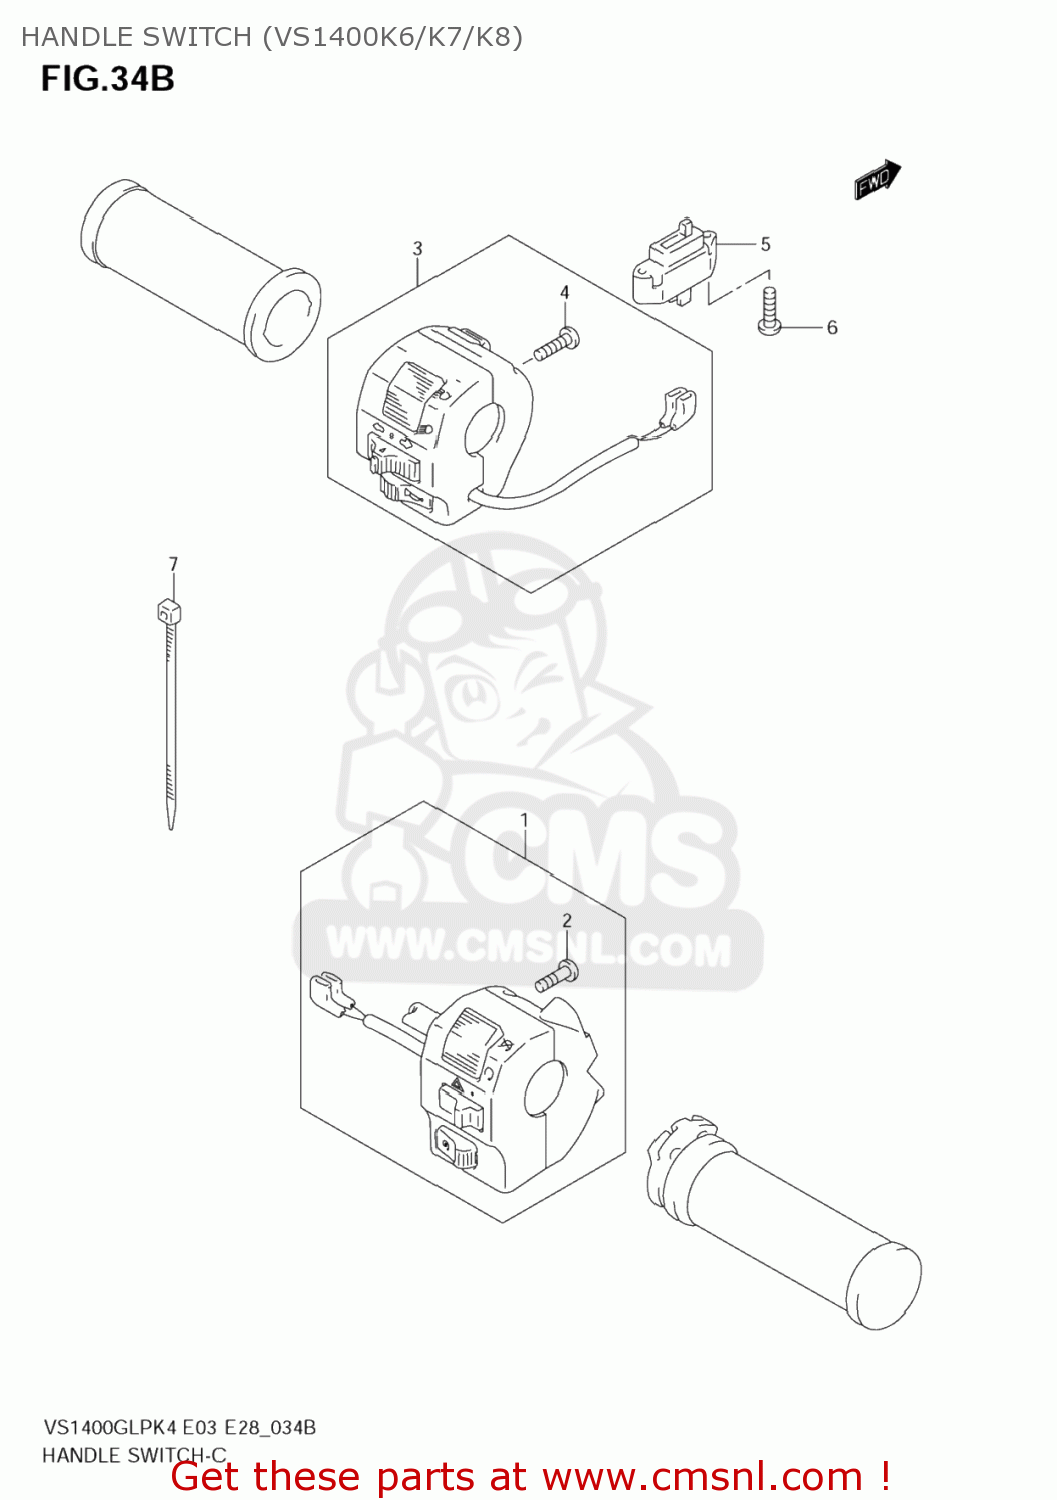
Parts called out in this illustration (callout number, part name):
1	SWITCH ASSY,HANDLE,R
2	SCREW
3	SWITCH ASSY,HANDLE,L
4	SCREW
5	SWITCH ASSY,CLUTCH
6	SCREW
7	CLAMP(L:145)
